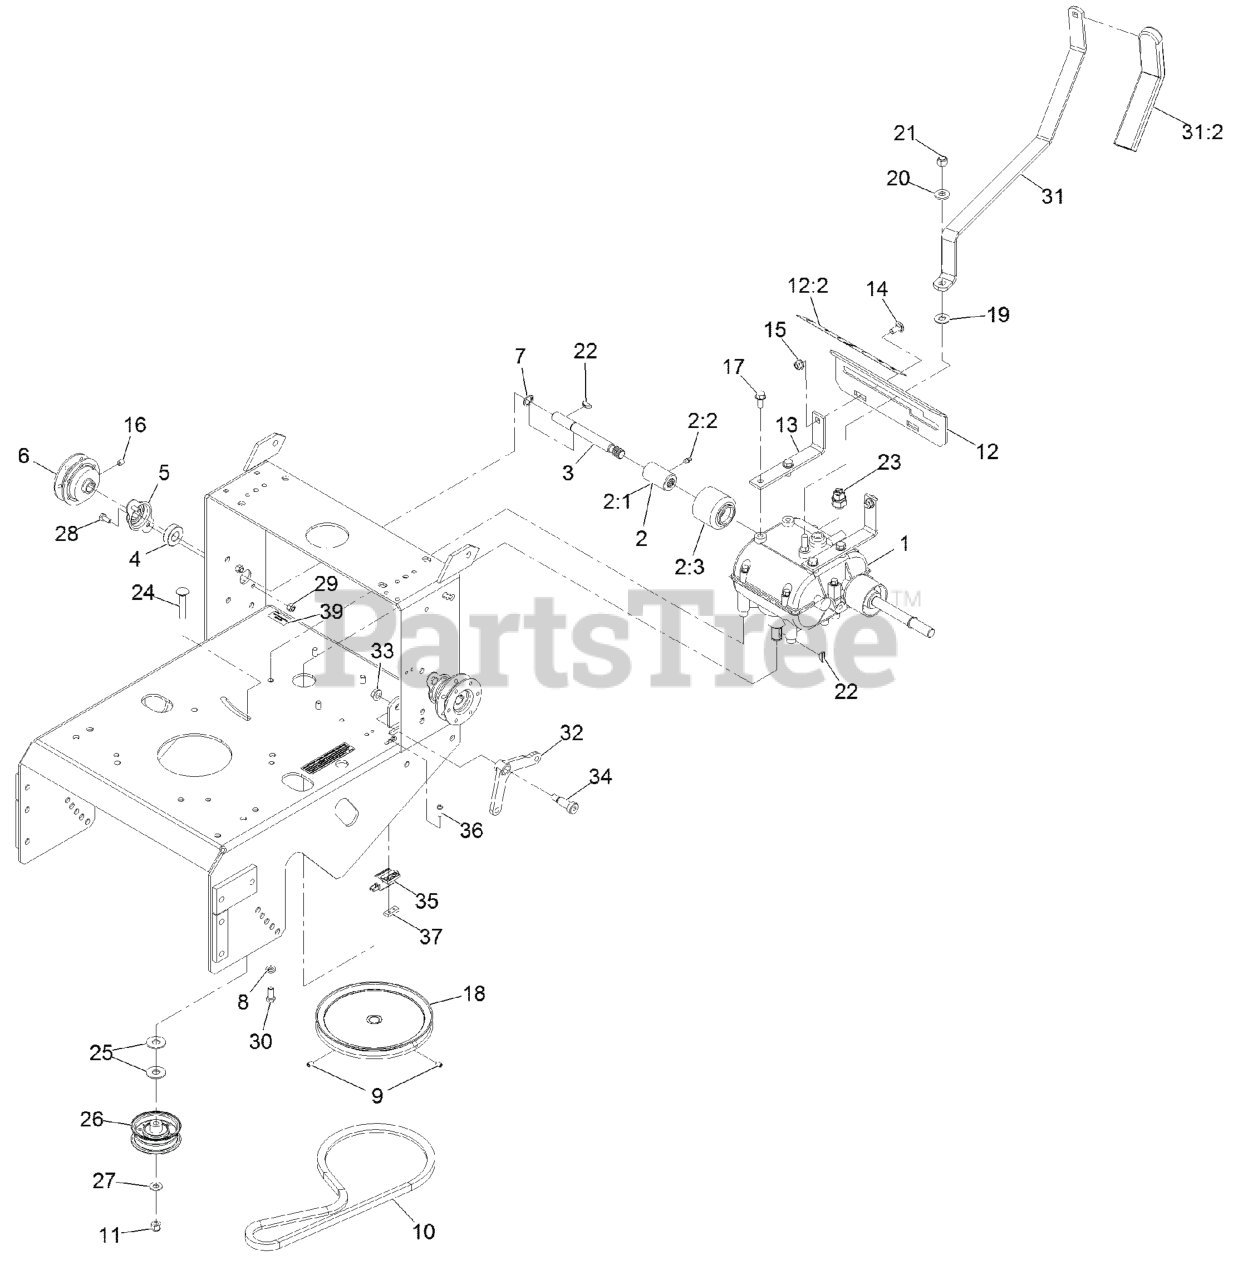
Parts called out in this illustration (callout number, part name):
1	TRANSMISSION-5 SPEED
2	ASM,COUPLER/ZERK
2:1	COUPLER
2:2	FITTING-GREASE
2:3	GUARD-COUPLER
3	SHAFT-TRANSMISSION
4	BEARING-SHAFT
5	FLANGE-OUTPUT
6	SHEAVE-TRANSMISSION
7	RING-RETAINING
8	WASHER-LOCK
9	SCREW-HSH
10	BELT,TRANS DRIVE
11	NUT-LOCK, NI
12	PLATE,SHIFTER W/DECAL
12:2	DECAL-SPEED, GROUND
13	BRACKET-PLATE, SHIFT
14	BOLT-CARR
15	NUT-HF, NI
16	SETSCREW
17	SCREW-THD ROLL, HWH
18	SHEAVE-TRANSMISSION
20	WASHER-BELLEVILLE
21	NUT-LOCK
22	KEY-WOODRUFF
23	SWITCH-START, NEUTRAL
24	SCREW-CARR
25	WASHER-FLAT
26	PULLEY-IDLER, FLAT
27	WASHER-FLAT
28	SCREW-HH
29	NUT-LOCK, NI
30	SCREW-HH
31	ASM,SHIFT LEVER
31:2	GRIP,FOAM
32	BELLCRANK
33	NUT-HHF, WHIZ
34	BOLT-SHOULDER
35	SWITCH-OPEN, NORMALLY
36	SCREW-PPH
37	PLATE-TAPPED
39	Decal-Patent
